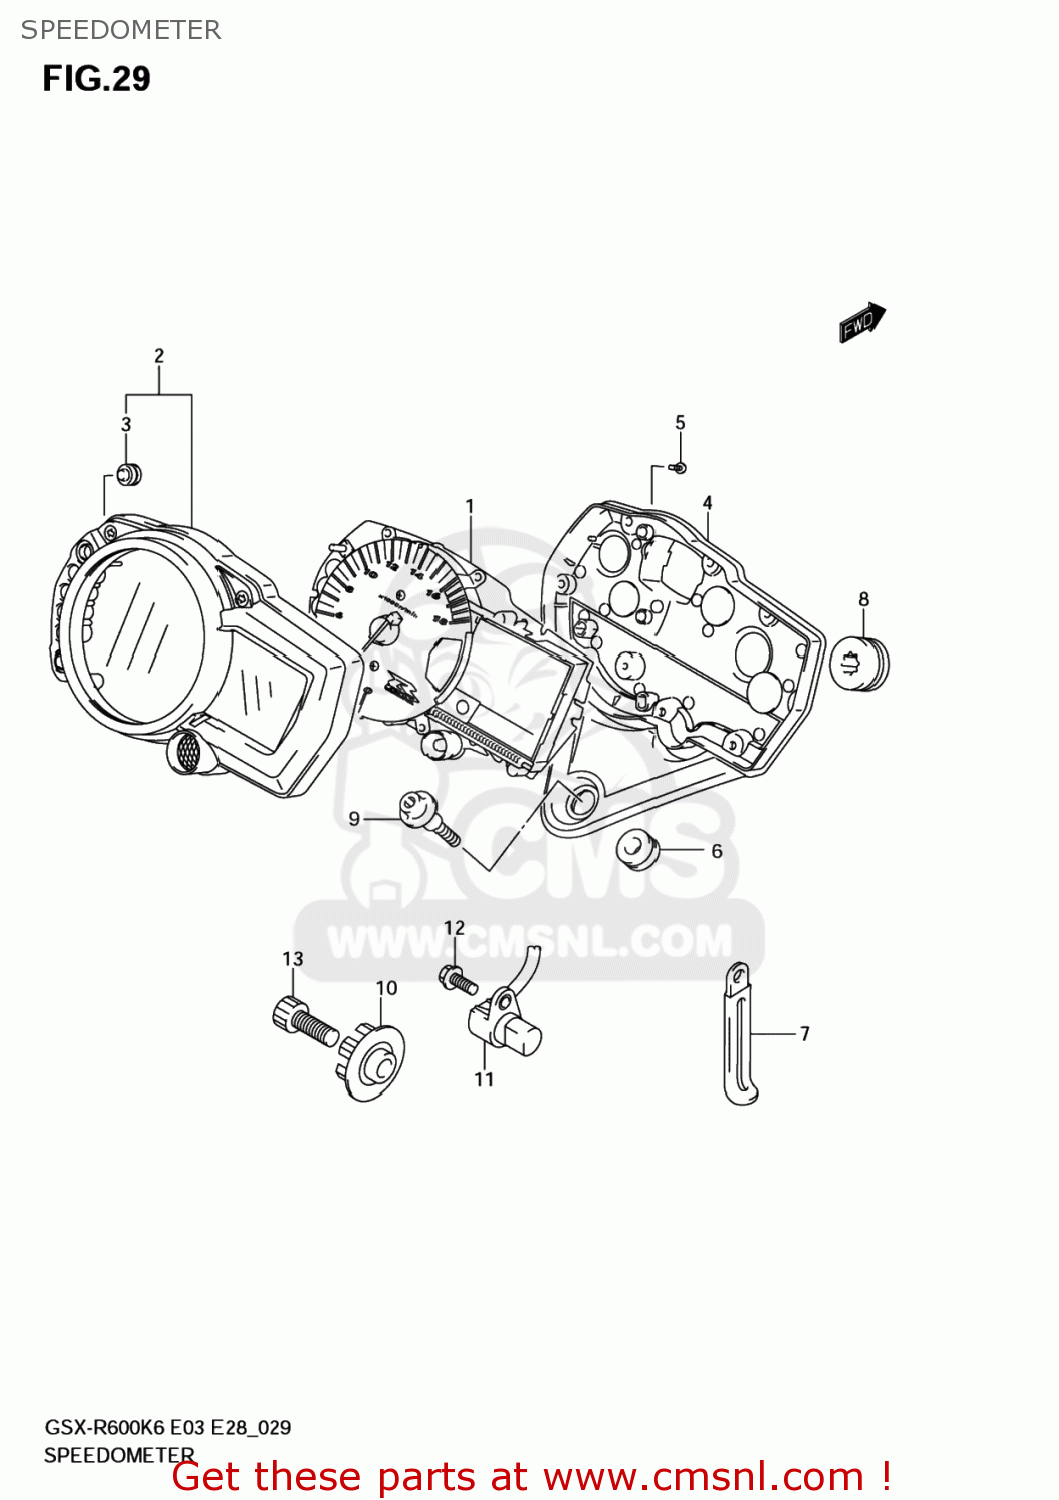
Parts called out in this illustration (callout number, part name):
1	SPEED & TACHOMETER ASSY
2	CASE,UPR
3	RUBBER,SWITCH
4	CASE,LWR
5	SCREW(3X16)
6	CUSHION,METER
7	CLAMP(L:45)
8	CUSHION
9	SCREW,SPEEDOMETER
10	ROTOR,SPEED
11	SENSOR,SPEED
12	BOLT
13	BOLT
